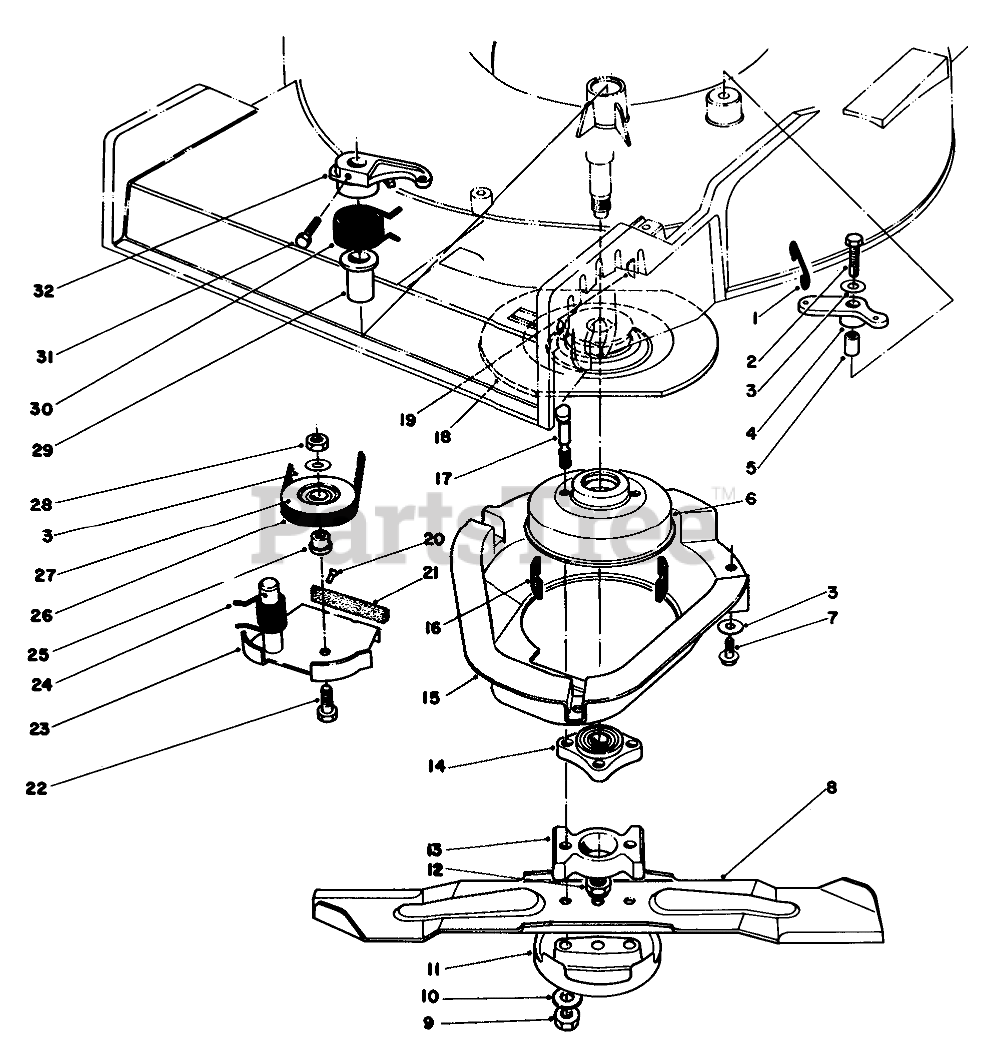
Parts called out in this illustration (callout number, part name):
1	LINK-CONTROL
2	SCREW-HH
3	WASHER-PLAIN
4	BELLCRANK
5	SLEEVE-BELLCRANK
6	Brake Drum
7	SCREW-HWHTF
8	BLADE-21in
9	NUT-LOCK
10	WASHER
11	Anti Scalp Cup
12	NUT-LOCK, NI
13	Spacer Blade
14	HUB ASM
15	SHIELD BBC
16	DAMPENER-VIBRATION
17	BOLT-BLADE
18	Flywheel
19	KEY-WOODRUFF
20	.185 DIA X .375 RT +
21	Paid
22	SCREW-HH
23	Brake Plate (Incl. Ref. #20 & 21)
24	SPRING-TORSION
25	HUB-PULLEY, IDLER
26	V-Belt
27	PULLEY-IDLER
28	NUT-LOCK, NI
29	BUSHING PM
30	SPRING-TORSION
31	SCREW-HH
32	LEVER
